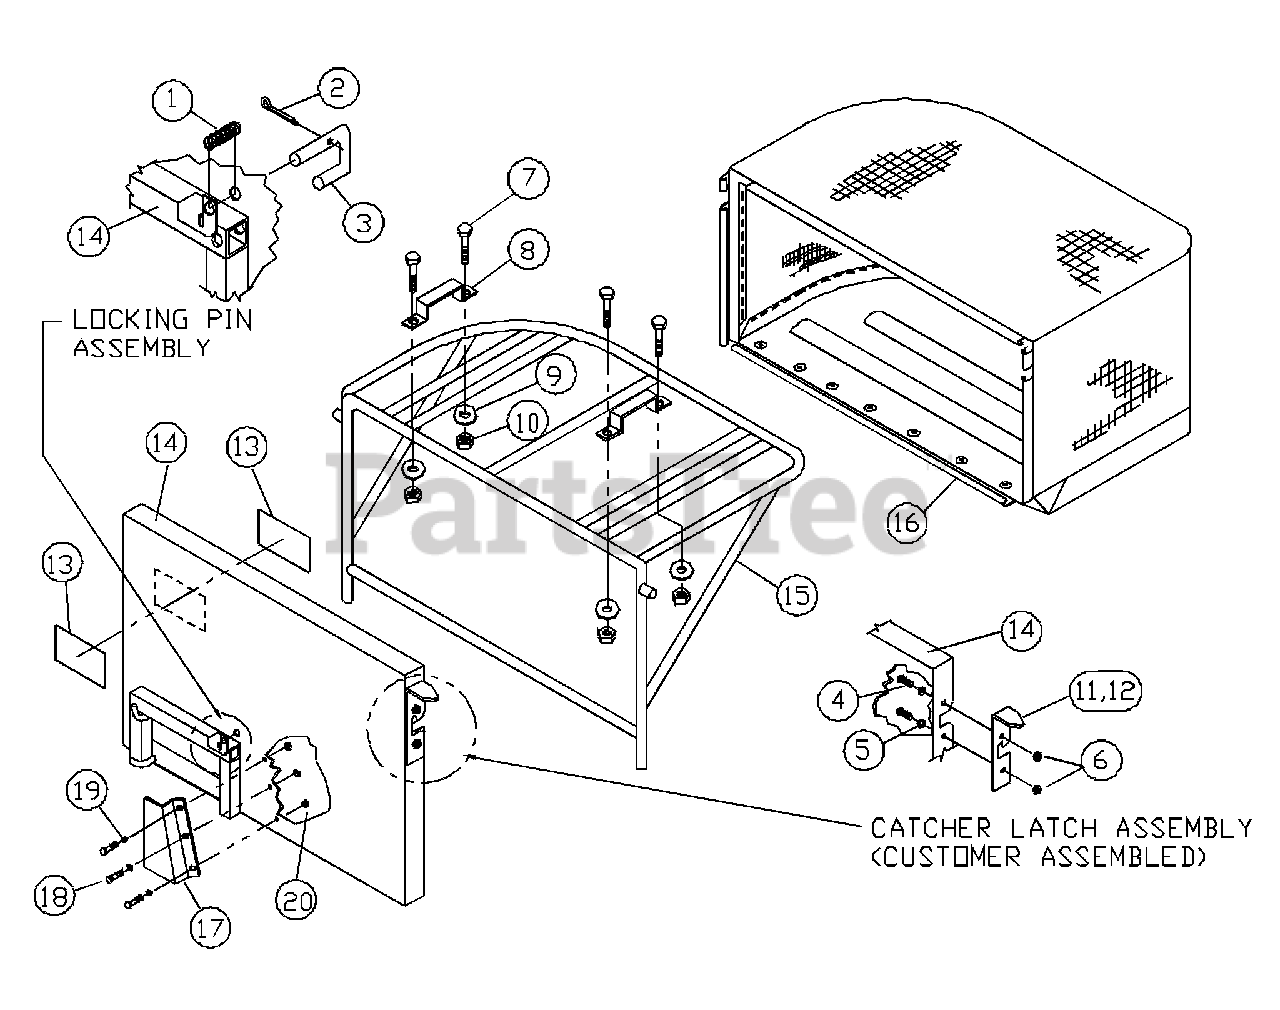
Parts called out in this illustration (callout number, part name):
1	Compression Spring
2	Locking Pin
3	3/32 x 1/2 Cotter Pin
4	10-24 x 5/8 Panhead Screw
5	1/4 Dia. Spring Washer
6	10-24 Nyloc Nut
7	1/4-20 x 1 HH Capscrew
8	Hopper Handle
9	1/4 Flat Washer
10	1/4-20 Nyloc Nut
11	Catcher Latch, Right
12	Catcher Latch, Left
13	Warning Decal
15	Hopper Frame
16	Fabric Bag
17	Adapter Shield
18	5/16C X 3/4 HCS
19	Washer Flat 5/16
20	Nut 5/16C
